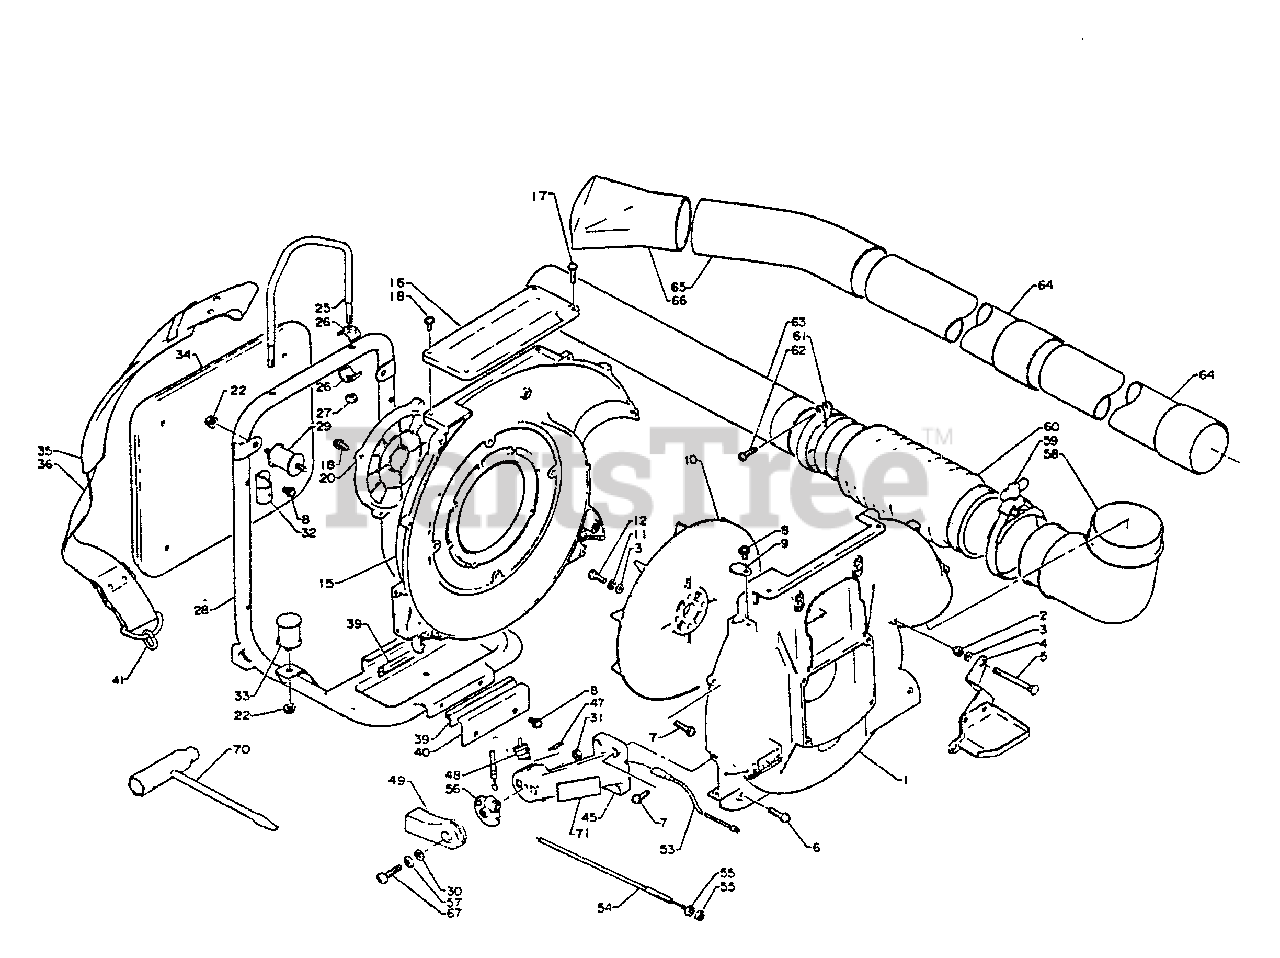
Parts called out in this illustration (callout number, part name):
1	COVER, FAN - OUTER
2	NUT - 5 -- CAP
3	WASHER - 5
4	BRACKET, MUFFLER COVER
5	BOLT, ELBOW
6	SCREW - 5X25
7	SCREW - 5X20
8	SCREW - 5X10
9	PLUG
11	LOCKWASHER - 5
12	BOLT - 5X16
15	COVER, FAN - INNER -- ORANGE
16	PLATE
17	SCREW - 6X20
18	SCREW - 6X15
20	GUARD, DEBRIS
22	NUT - 6 -- FLANGE
27	LOCKNUT - 6
28	FRAME, BACKPACK
30	WASHER - 6
31	LOCKNUT - 6
32	BRACKET, CUSHION
34	CUSHION, BACKPACK
35	BACKPACK STRAP ASSY
36	BACKPACK STRAP ASSY
39	CUSHION, FUEL TANK
40	BRACKET, FUEL TANK
41	RING, STRAP
45	MOUNT, THROTTLE LEVER
47	LABEL - STOP
48	IGNITION SWITCH ASSY
49	TRIGGER, THROTTLE
54	CABLE, THROTTLE
58	TUBE, BLOWER - ELBOW
59	CLAMP
60	TUBE, BLOWER - FLEXIBLE
61	CLAMP KIT
62	SCREW - 5X25
63	TUBE, BLOWER - SWIVEL
64	TUBE, BLOWER - STRAIGHT
65	TUBE, BLOWER - CURVED
66	NOZZLE - FAN HEAD
67	SCREW - 6X25
70	T-WRENCH - 10X19mm
71	LABEL - CAUTION
74	LABEL - ECHO
75	LABEL - NOISE
